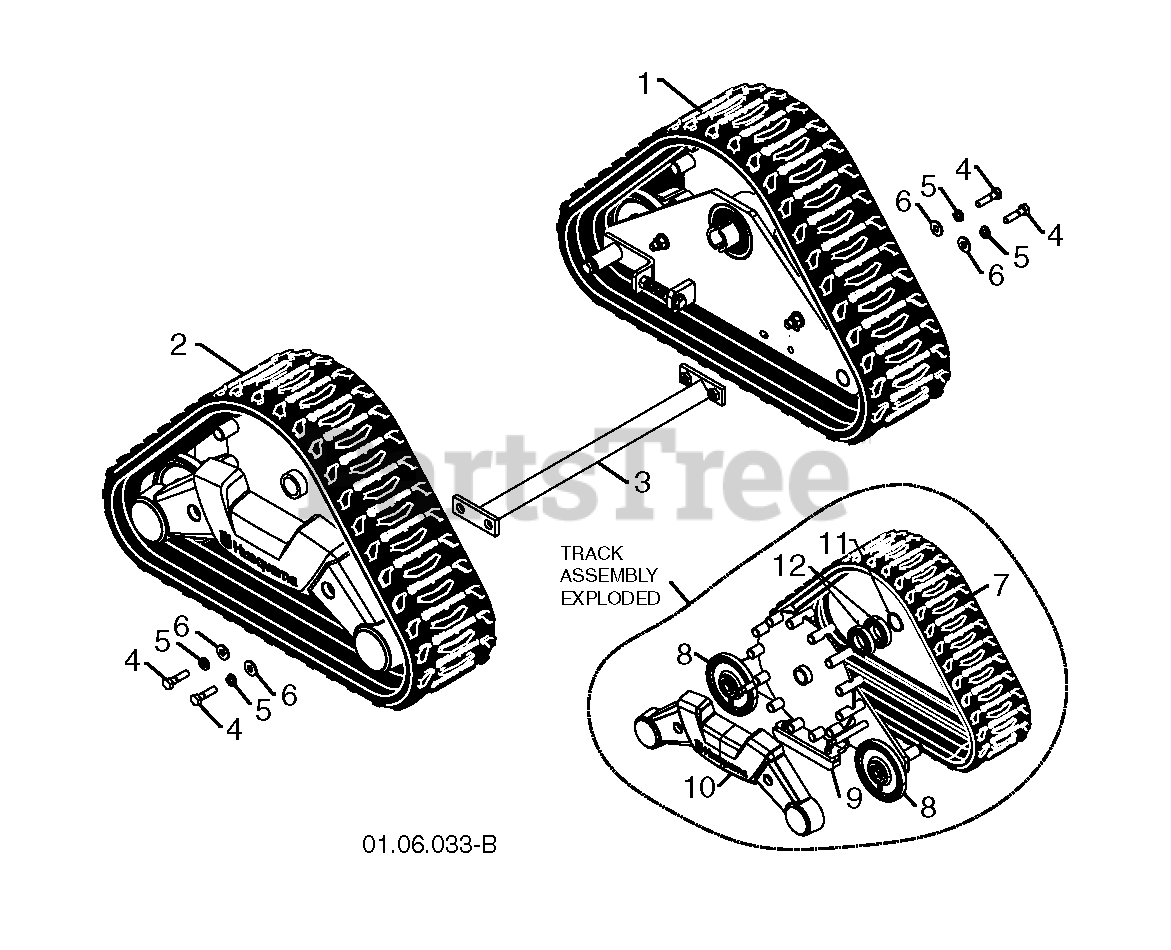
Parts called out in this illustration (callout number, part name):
1	WHEEL.ASM.TRACK.LH.12.SNOW
2	WHEEL.ASM.TRACK.RH.12.SNOW
3	SUPPORT.BRACE.ASM.TRACK.12
4	CAPSCREW.HEXHD.5/16X1.25.
5	LOCKWASHER
6	WASHER
7	BELT.TRACK.HYDRO.SNOW
8	WHEEL.IDLER.TRACK.SNOW
9	GUIDE.TRACK.SNOW
10	COVER.SIDE.TRACK
11	SNAP RING.1.25
12	BEARING.BALL.SHIELD.TRACK.SNOW
